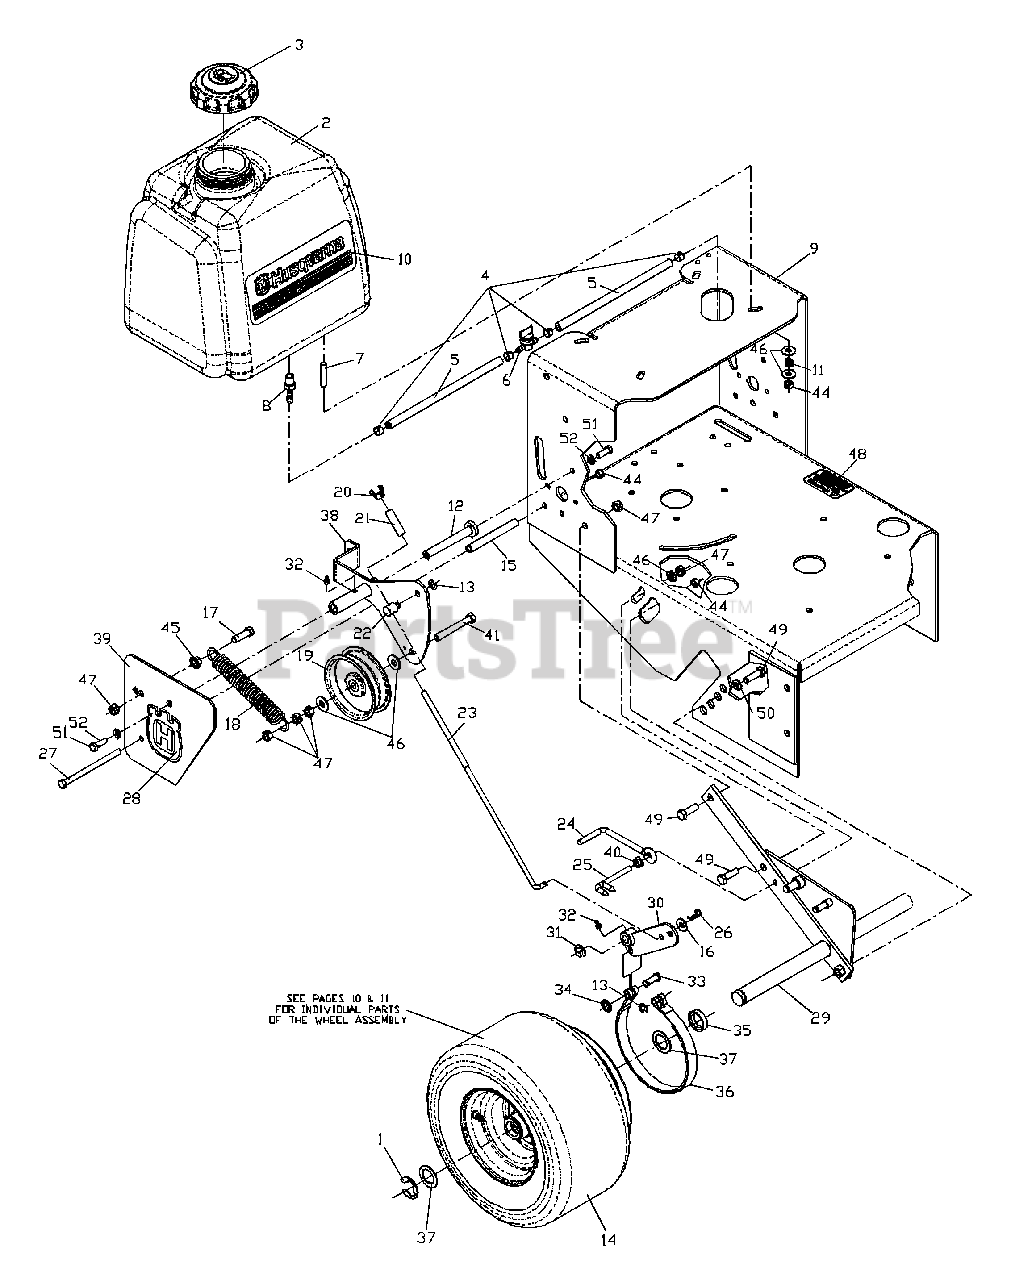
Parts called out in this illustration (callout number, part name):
1	E-RING 1"
3	GAS CAP
4	HOSE CLAMP
5	GAS LINE 10"
6	FULE VALVE
9	REAR DECK W/DECALS
10	DECAL, W3613
10	DECAL, W4815
12	SHOULDER PIVOT TUBE
13	E-RING 3/8"
14	WHEEL ASSEMBLY
15	LONG SPACER
16	WASHER 5/16 FLAT
17	HCS 3/8 X 1.250
19	IDLER PULLEY
20	WING NUT 5/16 NYLOC
24	BELT GUIDE
26	HAIR PIN #2
27	HCS 5/16 X 5.0
28	DECAL, CROWN
29	AXLE WELDMENT
30	BRAKE ARM, RT.
31	E-RING 1/2"
32	ZERK
33	CLEVIS PIN
34	BOLT RET. 3/8
36	BRAKE BAND
37	MACH. BUSHING
38	IDLER ARM, RT.
38	IDLER ARM, LT.
41	TAP BOLT 3/8 X 3.0
42	NUT 1/4 LOCK
43	HCS 1/4 X 1.0
44	NUT 5/16 LOCK
46	WASHER 3/8 FLAT
47	NUT 3/8 LOCK
48	DECAL, PROP 65
49	HCS 3/8 X 1.0
50	WASHER 3/8 LOCK
51	HCS 5/16 X 1.0
52	WASHER 5/16 LOCK
